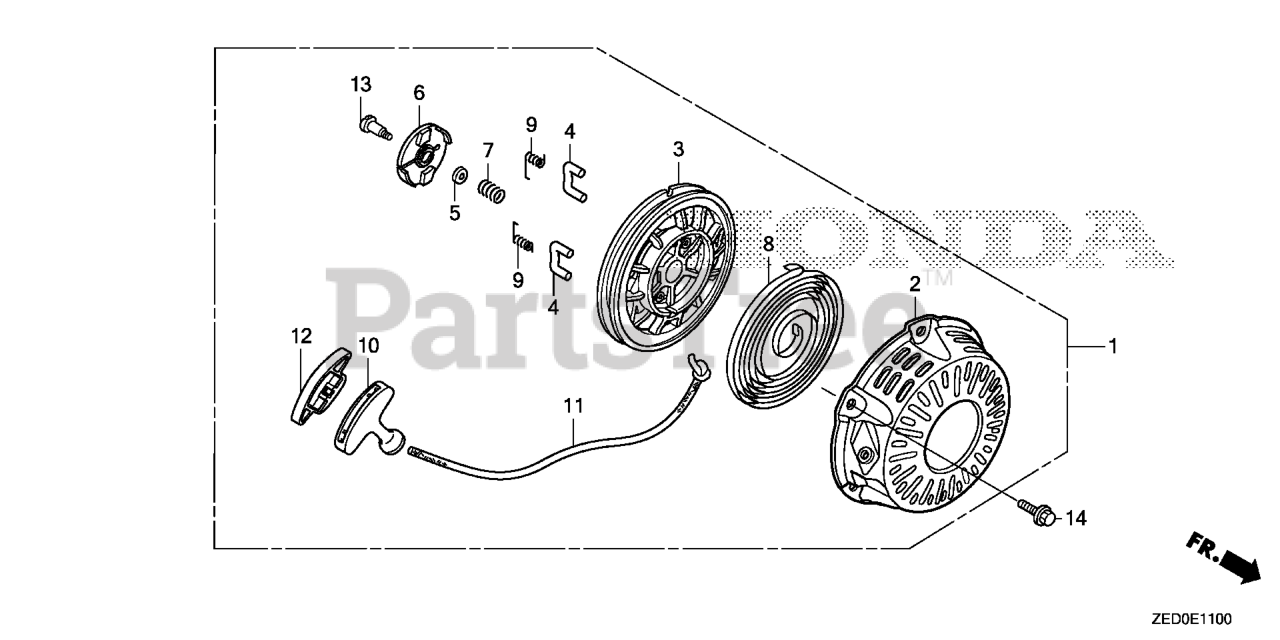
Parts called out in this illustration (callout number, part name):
1	STARTER ASSY., RECOIL *R280* (POWER RED)
1	STARTER ASSY., RECOIL *NH1* (BLACK)
2	CASE, RECOIL STARTER *R280* (POWER RED)
2	CASE, RECOIL STARTER *NH1* (BLACK)
3	REEL, RECOIL STARTER (BLACK)
4	RATCHET, STARTER
5	PLATE, FRICTION
6	GUIDE, RATCHET
7	SPRING, FRICTION
8	SPRING, RECOIL STARTER
9	SPRING, RETURN
10	KNOB, RECOIL STARTER
11	ROPE, RECOIL STARTER (#5X55")
12	KNOB, REINFORCEMENT
13	SCREW, SETTING
14	BOLT, FLANGE (6X10)
14	BOLT, FLANGE (6X8)
